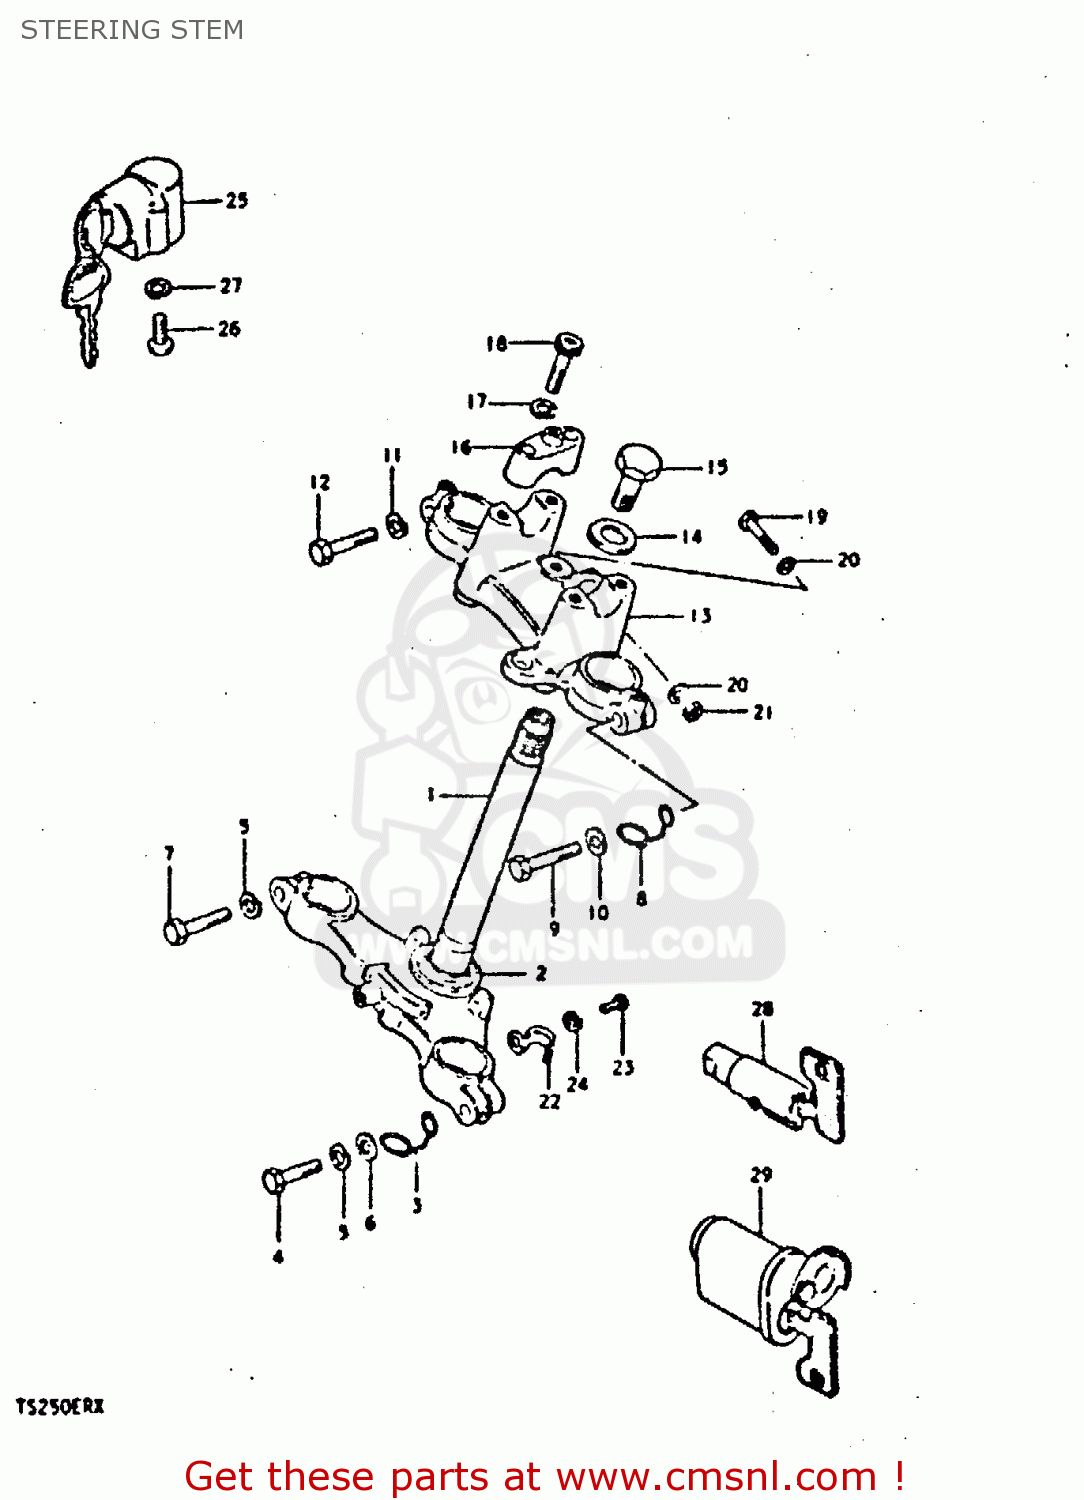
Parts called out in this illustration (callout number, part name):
1	STEM,STEERING
2	RACE,STEERING OUTER LWR
3	CLIP
4	BOLT 12X45
5	WASHER,LOCK 12
6	WASHER
7	BOLT
8	GUIDE,CABLE
9	BOLT 10X40
10	WASHER
11	LOCK WASHER
12	BOLT 10X40
13	HEAD,STEERING STEM
14	WASHER
15	BOLT,STEERING STEM HEAD
16	CLAMP,HANDLE HOLDER UPR
17	LOCK WASHER
18	BOLT 8X35
19	BOLT 8X55
20	WASHER
21	NUT
22	CLIP,BRAKE CABLE
23	SCREW
24	LOCK WASHER
25	LOCK ASSEMBLY,STEERING
26	SCREW
27	LOCK WASHER
